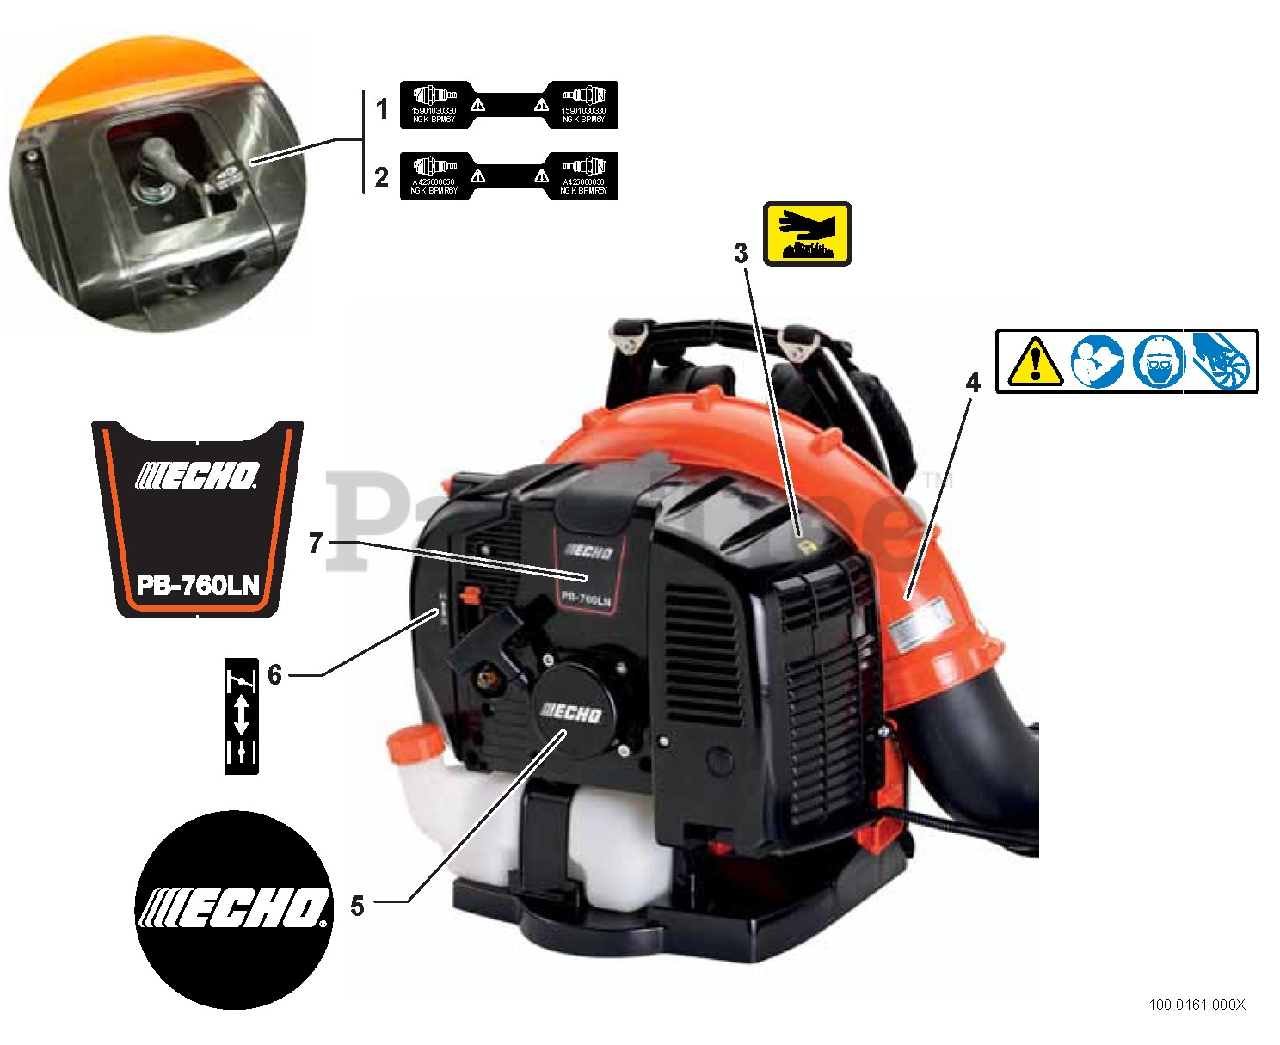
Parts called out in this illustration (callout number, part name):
1	LABEL - SPARK PLUG -- BPM-6Y
2	LABEL - SPARK PLUG -- BPMR-6Y
3	LABEL - HOT SURFACE
4	LABEL - CAUTION
5	LABEL - ECHO
6	LABEL - CHOKE
7	LABEL - MODEL PB-760LN
